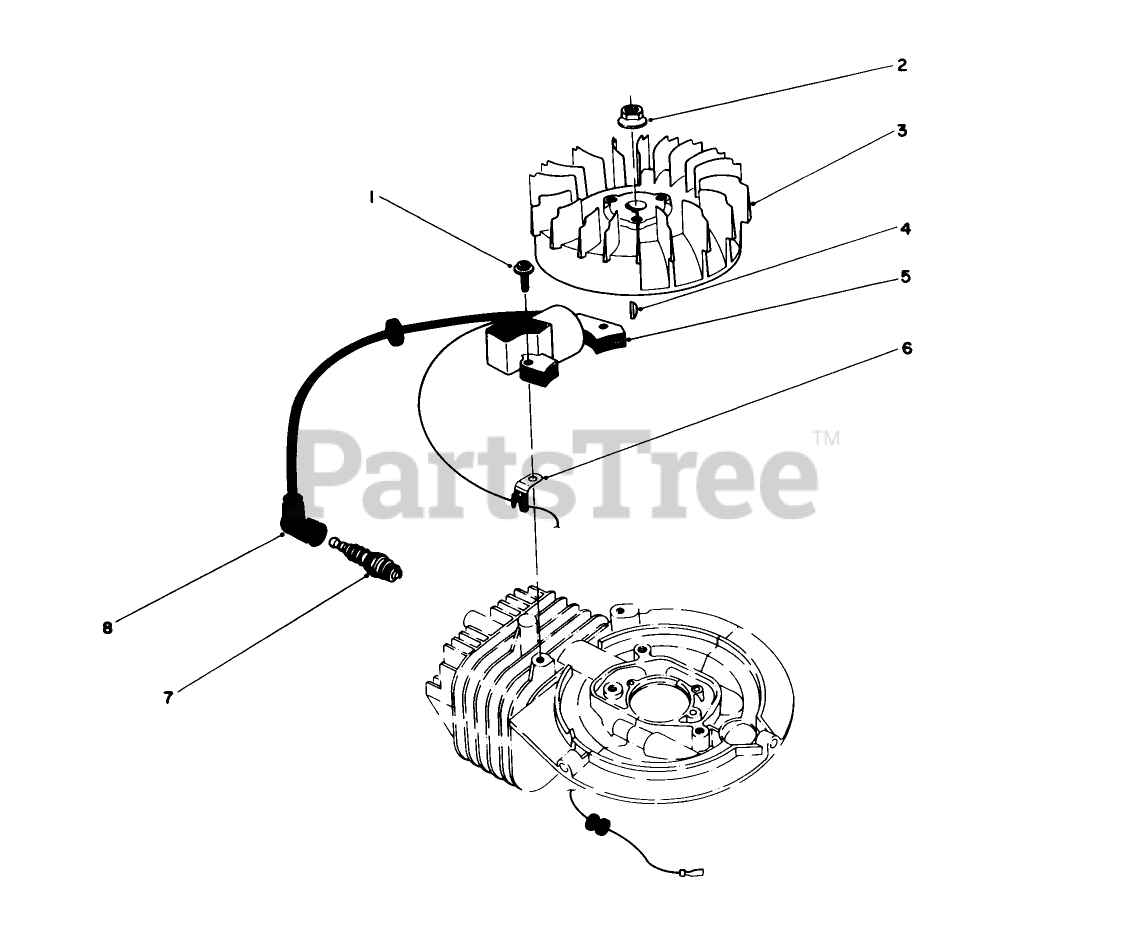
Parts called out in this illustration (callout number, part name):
3	FLYWHEEL
5	COIL-MAGNETO
6	CLAMP
8	CAP-SPARKPLUG
